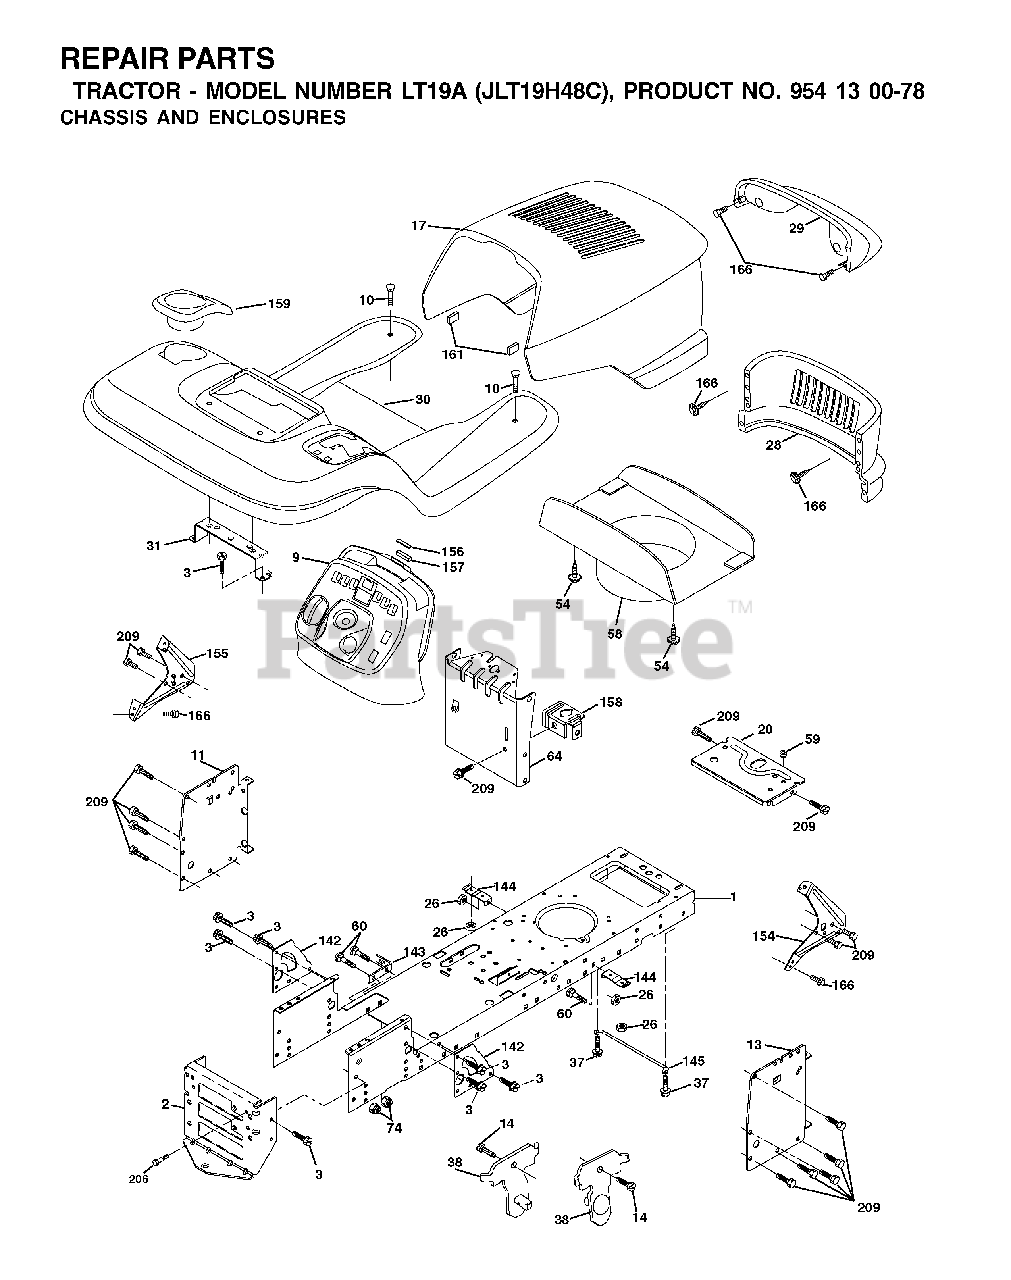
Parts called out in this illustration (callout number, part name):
1	CHASSIS STAMPING
2	DRAWBAR, 12GA
3	SCREW 3/8-16X3/4
10	BOLT D
13	PANEL DASH RH
26	NUT
38	BRACKET.ASM.PIVOT.MOWER.REAR
58	DUCT HOOD
59	BUSHING 1.375 OD
64	DASH LOWER
74	LOCKNUT
142	PLATE REINFORCEMENT
143	BRACKET, SWAY BAR
144	BRKT, FOOT REST
145	ROD PIVOT CHASSIS/HOOD
161	EXTRUSION BUMPER
166	SCREW
206	SHOULDER BOLT 5/16-18TT
209	SCREW, 3/8-16X3/4
